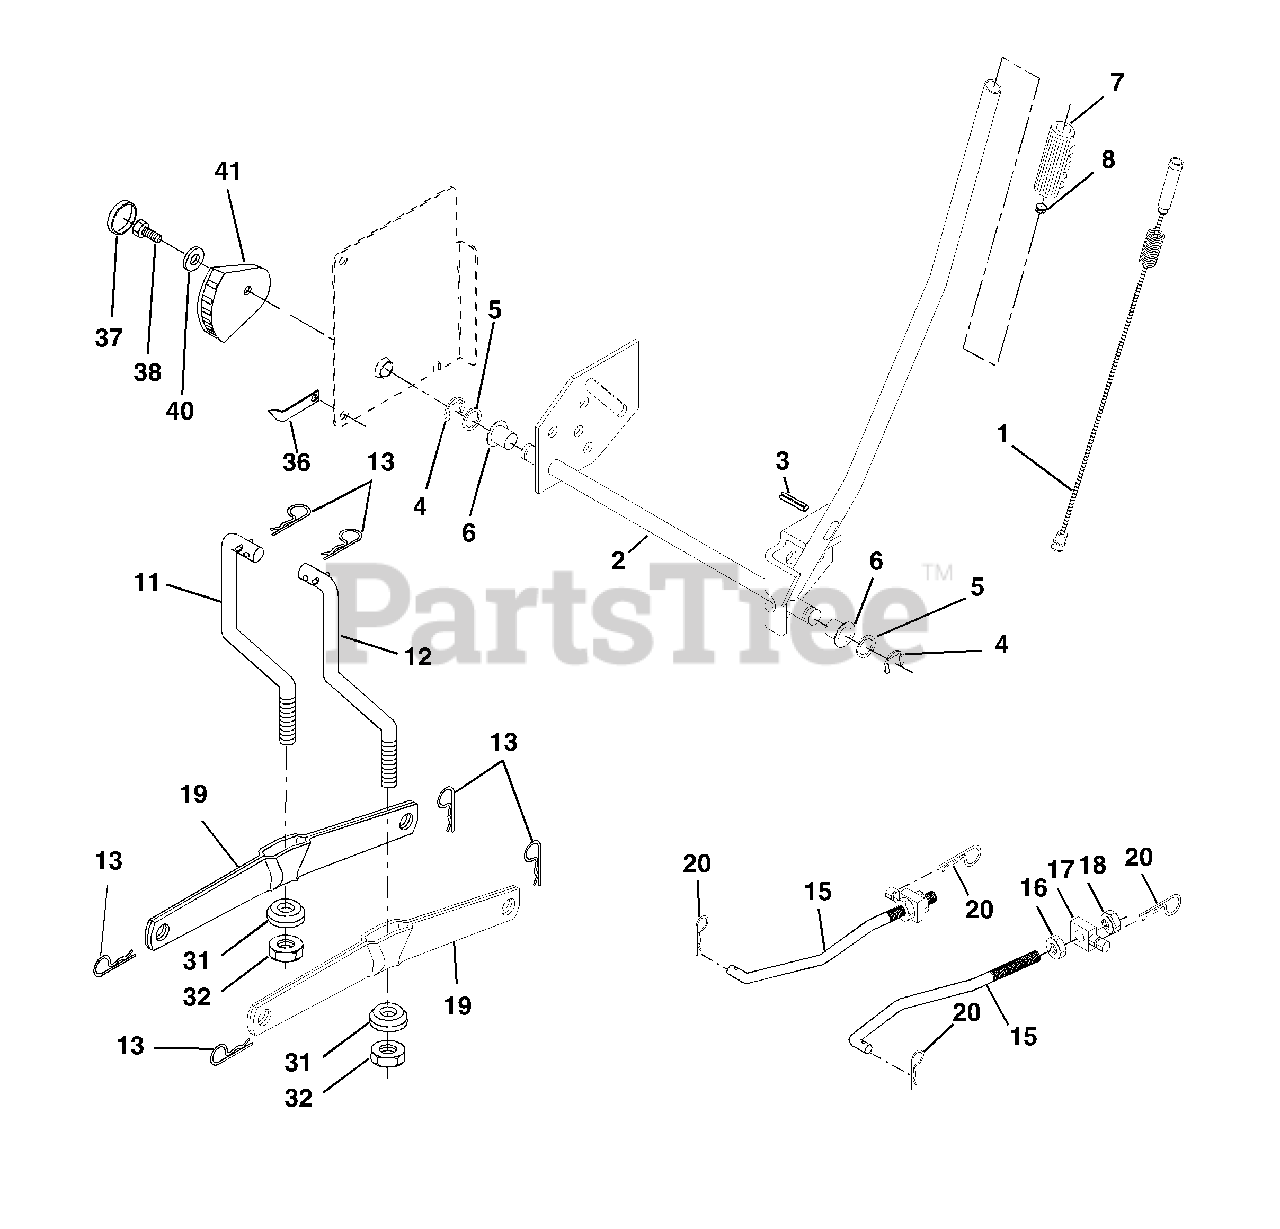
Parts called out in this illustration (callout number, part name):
1	Wire Asm Inner/Sprg W/plunger LT
2	Shaft Asm Lift RH w/Inf
3	Pin Groove 1 500 Zinc
4	E Ring #5133-62
5	Washer 21/32 X 1 X 21 Ga
6	Bearing Nylon Blk 629 Id
7	Grip Handle
8	Button Plunger Yellow
11	Link Lift LH Fixed Length
12	Link Lift RH Fixed Length
13	Retainer Spring
15	Link Front
16	Nut Jam Hex 1/2-13 Unc
17	Trunnion
18	Nut Lock w/Wsh 1/2-13 Unc
19	Arm Suspension Rear
20	Retainer Spring
31	Bearing Pvt Lift
32	Nut Crownlock 3/8 - 24
36	Pointer Height Indicator
37	Plug Hole Blk 1.485/1.515 Dia.
38	Screw Thdrol 5/16-18 x 1
40	Washer 11/32 x 1-1/2 10 Ga.
41	Indicator Height STLT
